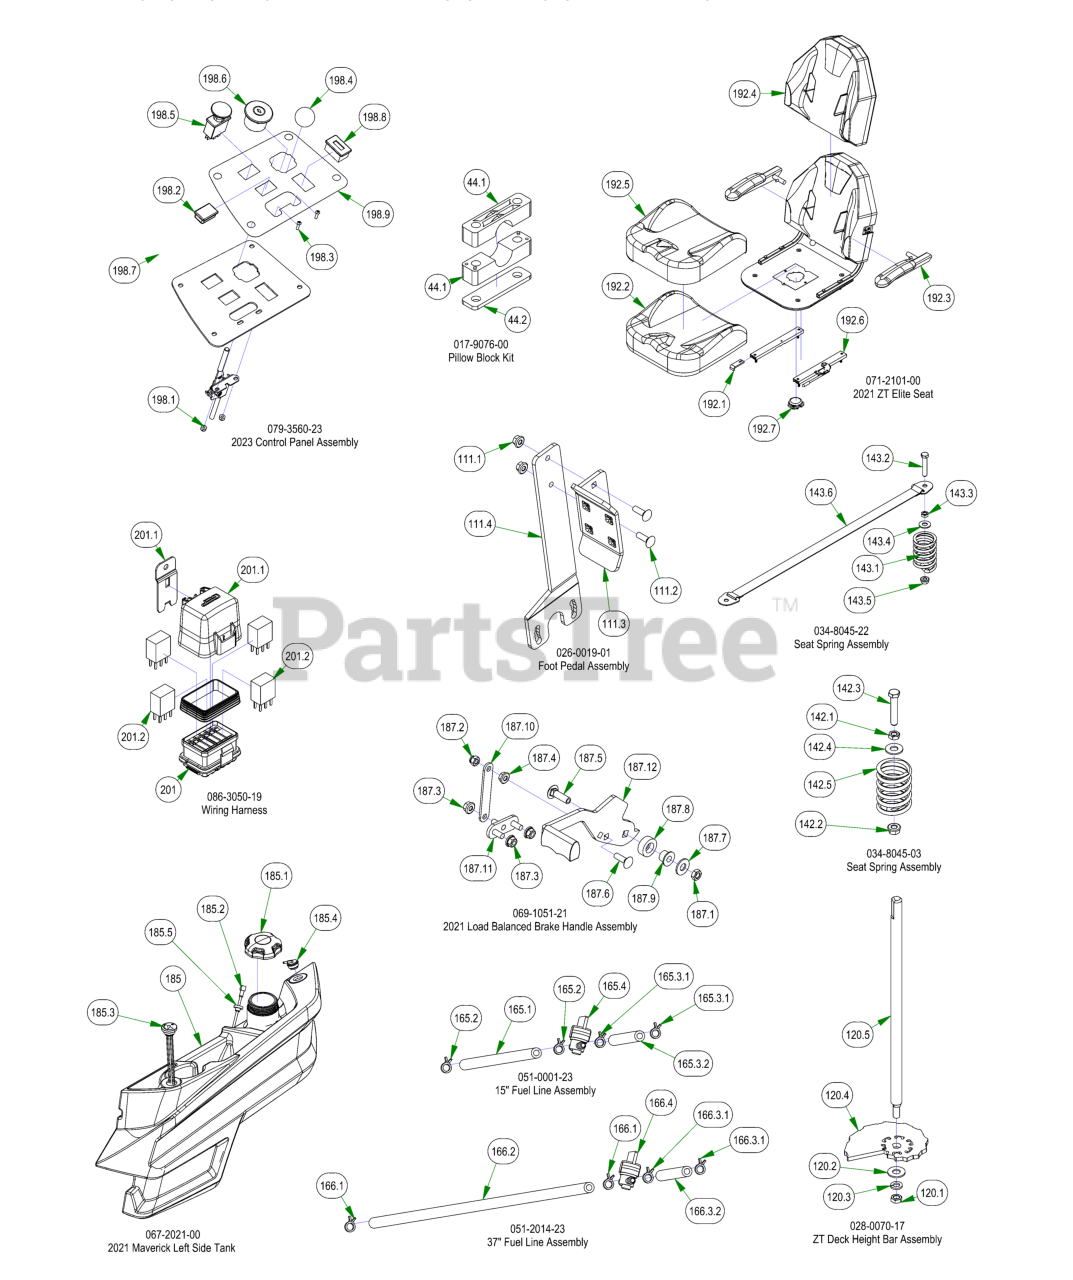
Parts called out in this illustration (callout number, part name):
44	Pillow Block Kit
44.1	Pillow Block MZ
44.2	Pillow Block Strap
111	Foot Pedal Assembly
111.1	5/16-18 NYLON INSERT FLANGE LOCKNUT ZINC
111.2	5/16-18 X 1 CARRIAGE BOLT (GR.8) ZINC
111.3	2017 MZ/ZT Shallow Foot Pedal
111.4	2017 MZ/ZT Deck Pedal Lever
120	ZT Deck Height Bar Assembly
120.1	3/8-24 HEX NUT ZINC YELLOW
120.2	3/8 FLAT WASHER USS (1" OD) ZINC
120.3	3/8 SPLIT LOCKWASHER ZINC
120.4	2017 MZ/ZT Cam Plate
120.5	2017 Deck Height Dial Rod ZT
142	Seat Spring Assembly
142.1	3/8-16 Half Jam Nut
142.2	3/8-16 HEX SERRATED FLANGE NUT HARD/ZINC
142.3	3/8-16 X 2 HEX CAP SCREW (GR.5) ZINC
142.4	3/8 FLAT WASHER USS (1" OD) ZINC
142.5	Seat Spring
143	Seat Spring Assembly
143.1	Seat Spring
143.2	3/8-16 X 2 HEX CAP SCREW (GR.5) ZINC
143.3	3/8-16 Half Jam Nut
143.4	3/8 FLAT WASHER USS (1" OD) ZINC
143.5	3/8-16 HEX SERRATED FLANGE NUT HARD/ZINC
143.6	Seat Strap with Buckles
165	15" Fuel Line Assembly
165.1	11" 1/4 Fuel Line
165.2	1/4 Fuel Hose Clamp
165.3	Fuel Line 4" Section with Clamps
165.3.1	1/4 Fuel Hose Clamp
165.3.2	4" 1/4 Fuel Line
165.4	2 Way Fuel Shut-Off Valve
166	37" Fuel Line Assembly
166.1	1/4 Fuel Hose Clamp
166.2	37" 1/4 Fuel Line
166.3	Fuel Line 4" Section with Clamps
166.3.1	1/4 Fuel Hose Clamp
166.3.2	4" 1/4 Fuel Line
166.4	2 Way Fuel Shut-Off Valve
185	2021 Maverick Left Side Tank
185.3	Fuel Gauge w/Grommet
185.4	Rollover Valve W/Grommet
185.5	Pick-Up Grommet
187	2021 Load Balanced Brake Handle Assembly
187.1	3/8-16 HEX JAM 2-WAY REVERSIBLE CENTER LOCKNUT ZINC
187.2	5/16-18 NYLON INSERT CAP LOCKNUT ZINC (BLK CAP)
187.3	5/16-18 NYLON INSERT FLANGE LOCKNUT ZINC
187.4	5/16-18 HEX SERRATED FLANGE NUT HARD/ZINC
187.5	3/8-16 X 1-1/4 CARRIAGE BOLT ZINC
187.6	5/16-18 X 1 CARRIAGE BOLT (GR.8) ZINC
187.7	3/8 FLAT WASHER USS (1" OD) ZINC
187.8	2015 Brake Lever Spacer
187.9	.377 ID X .625 OD X .500 HGT X .880 FLNG DIA X .060 FLNG THK
187.10	Brake Cable Extension Plate
187.11	Brake Load Balancer Lower Weldment
187.12	Load Balanced Brake Handle with Grip
192	2021 ZT Elite Seat
192.1	Black Seat stop from Seat King
192.2	Seat Cover Molded Foam for 071-2040-18/071-5080-18
192.3	2017 ZT/Maverick/2020 ZTElite/Avenger Arm Rest Kit
192.4	Back Cover for 071-2101-00
192.5	Seat Cover for 071-2101-00/071-2102-00
192.6	Seat Rails for Outlaw Seat/2020 ZT Elite/ZTAvenger
192.7	13/14 MZ/Outlaw Seat Switch
198	2023 Control Panel Assembly
198.1	10-24 Nylon Insert Locknut Zinc Orange Nylon
198.2	Light Plug
198.3	10-24 X 5/8 BS Button Head Bolt
198.4	Throttle Lever Assembly
198.5	PTO Engager
198.6	Ignition Switch
198.7	2022 Maverick HD control panel
198.8	Tachometer
198.9	2023 MZ/Magnum/ZT/Maverick Control Panel Decal
201	Wiring Harness
201.1	Relay Block Cover Replacement Kit
